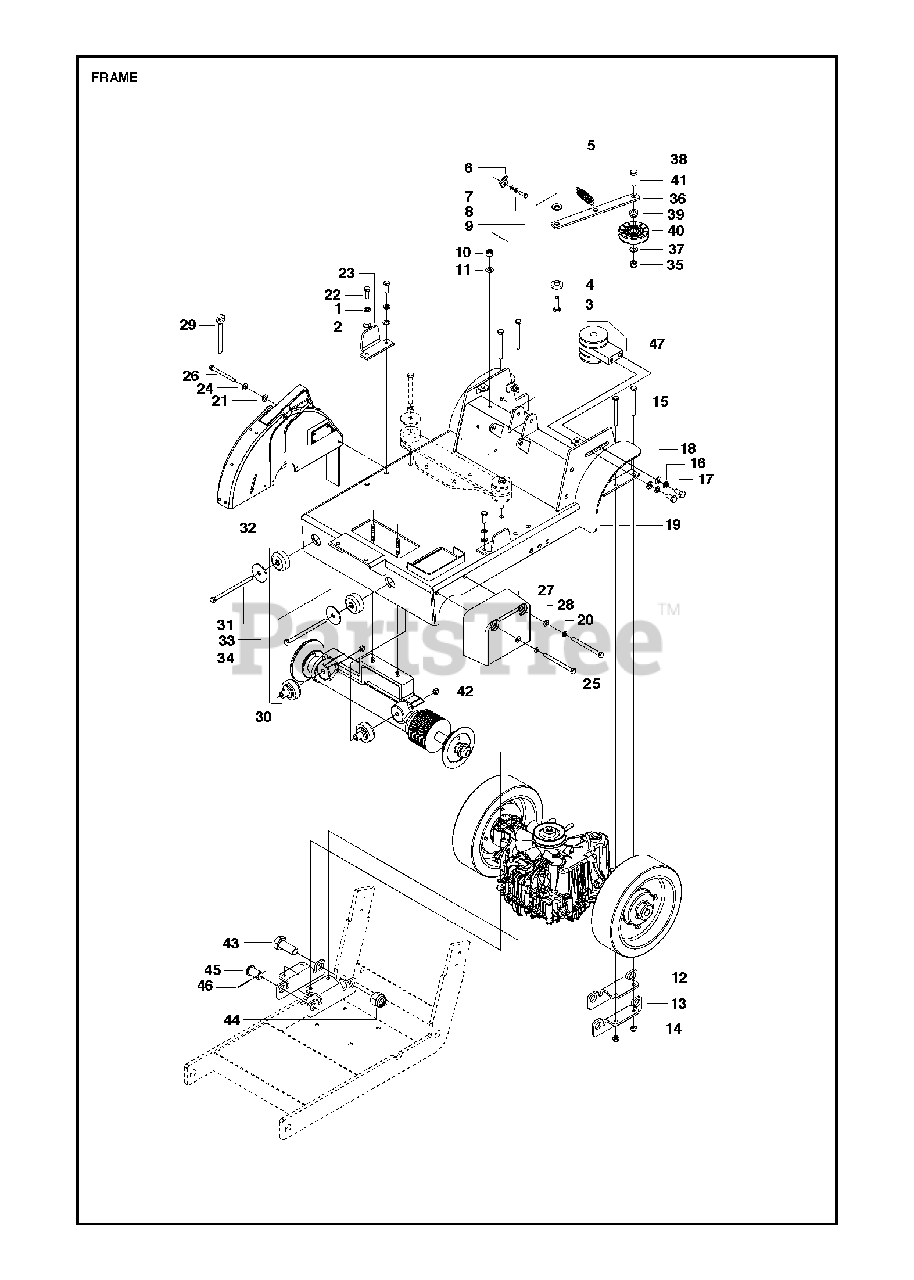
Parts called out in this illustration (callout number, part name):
1	SPRING WASHER
2	WASHER
10	HEXAGON LOCKING NUT
11	WASHER
14	HEXAGON LOCKING NUT
18	WASHER
20	SPRING WASHER
21	WASHER
24	SPRING WASHER
28	WASHER
31	HHCS. M10X1.5X130MM Z/P
35	HEXAGON LOCKING NUT
37	WASHER
42	HEXAGON LOCKING NUT
